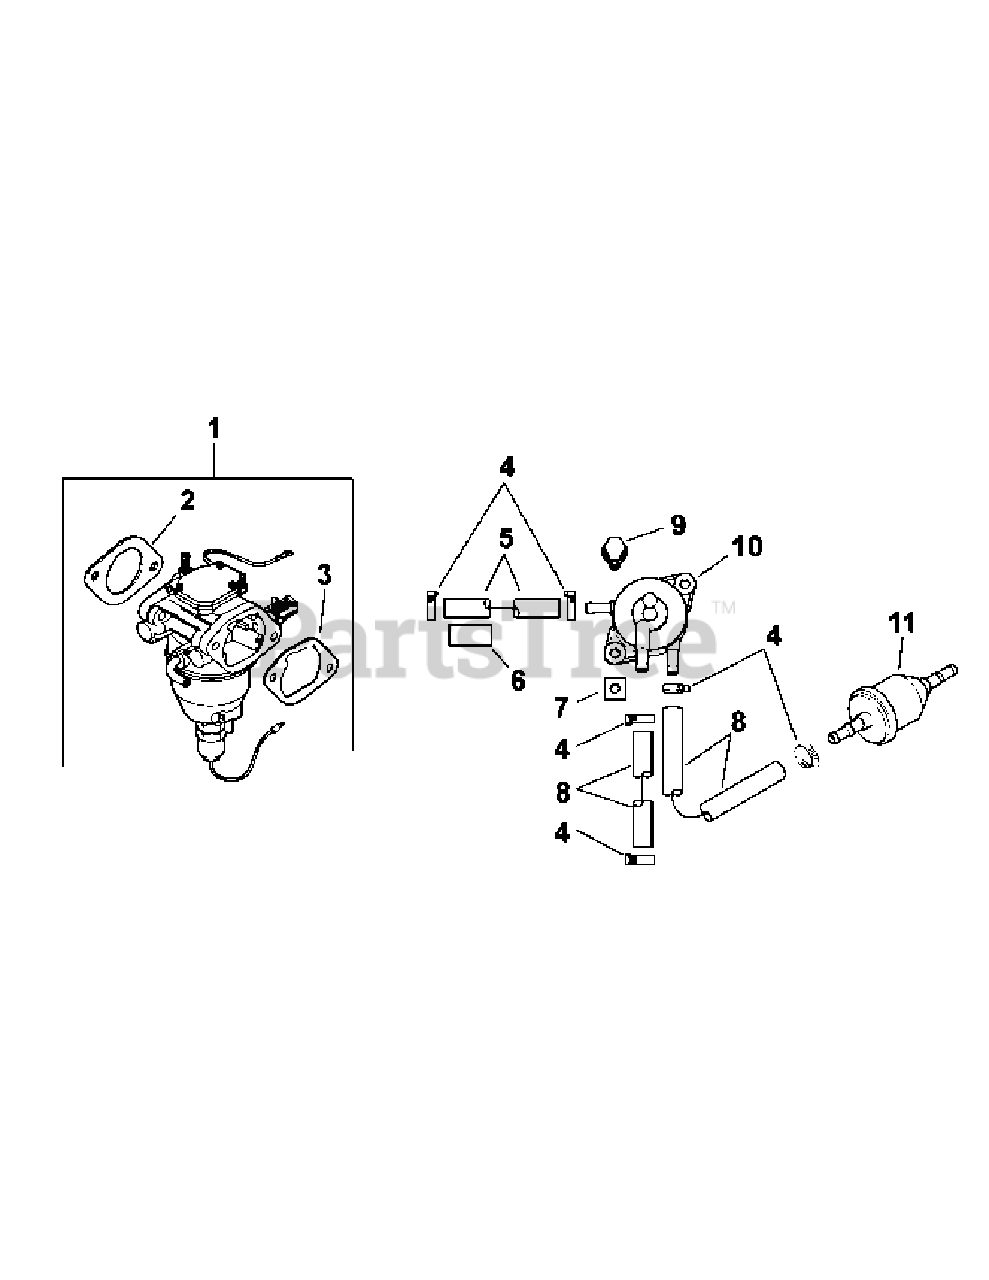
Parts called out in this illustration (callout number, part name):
1	Carburetor Kit w/ Gaskets (Inc. 2 & 3)
2	Carburetor Gasket
3	Air Cleaner Base gasket
4	Hose Clamp, 1/2"
5	Fuel Line, 11
6	Insulating Sleeve, 14
7	Plastic Nut, Black
8	Fuel Line, 24"
9	Tap Screw, M6 x 1.7 x 18
11	Fuel Filter
